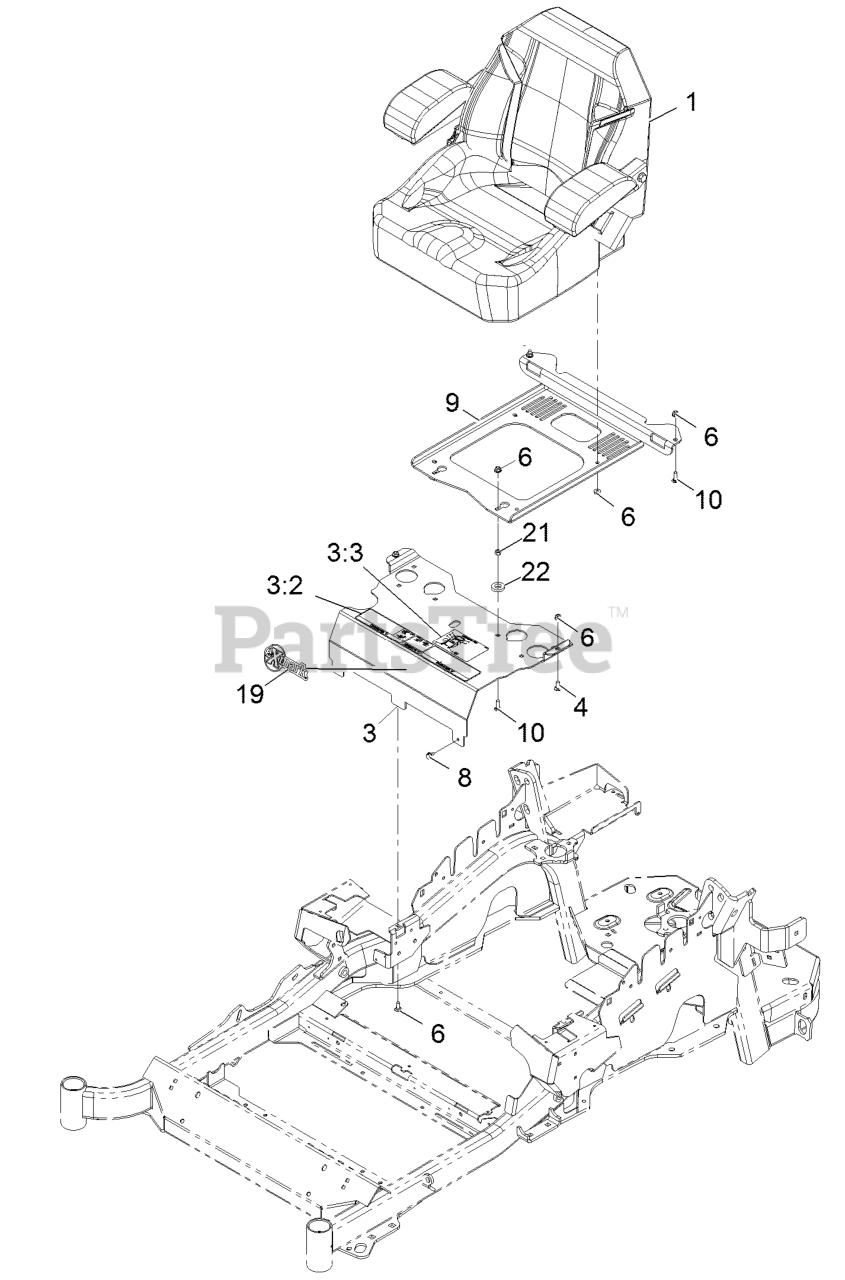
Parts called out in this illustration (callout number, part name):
3	MOUNT-SEAT
3:2	DECAL-CONSOLE
3:3	DECAL-SERVICE AID
4	SCREW-CARR
6	NUT-HF, NI
9	PLATE-SUPPORT, SEAT
10	SCREW-CARR
21	NUT-HEX
